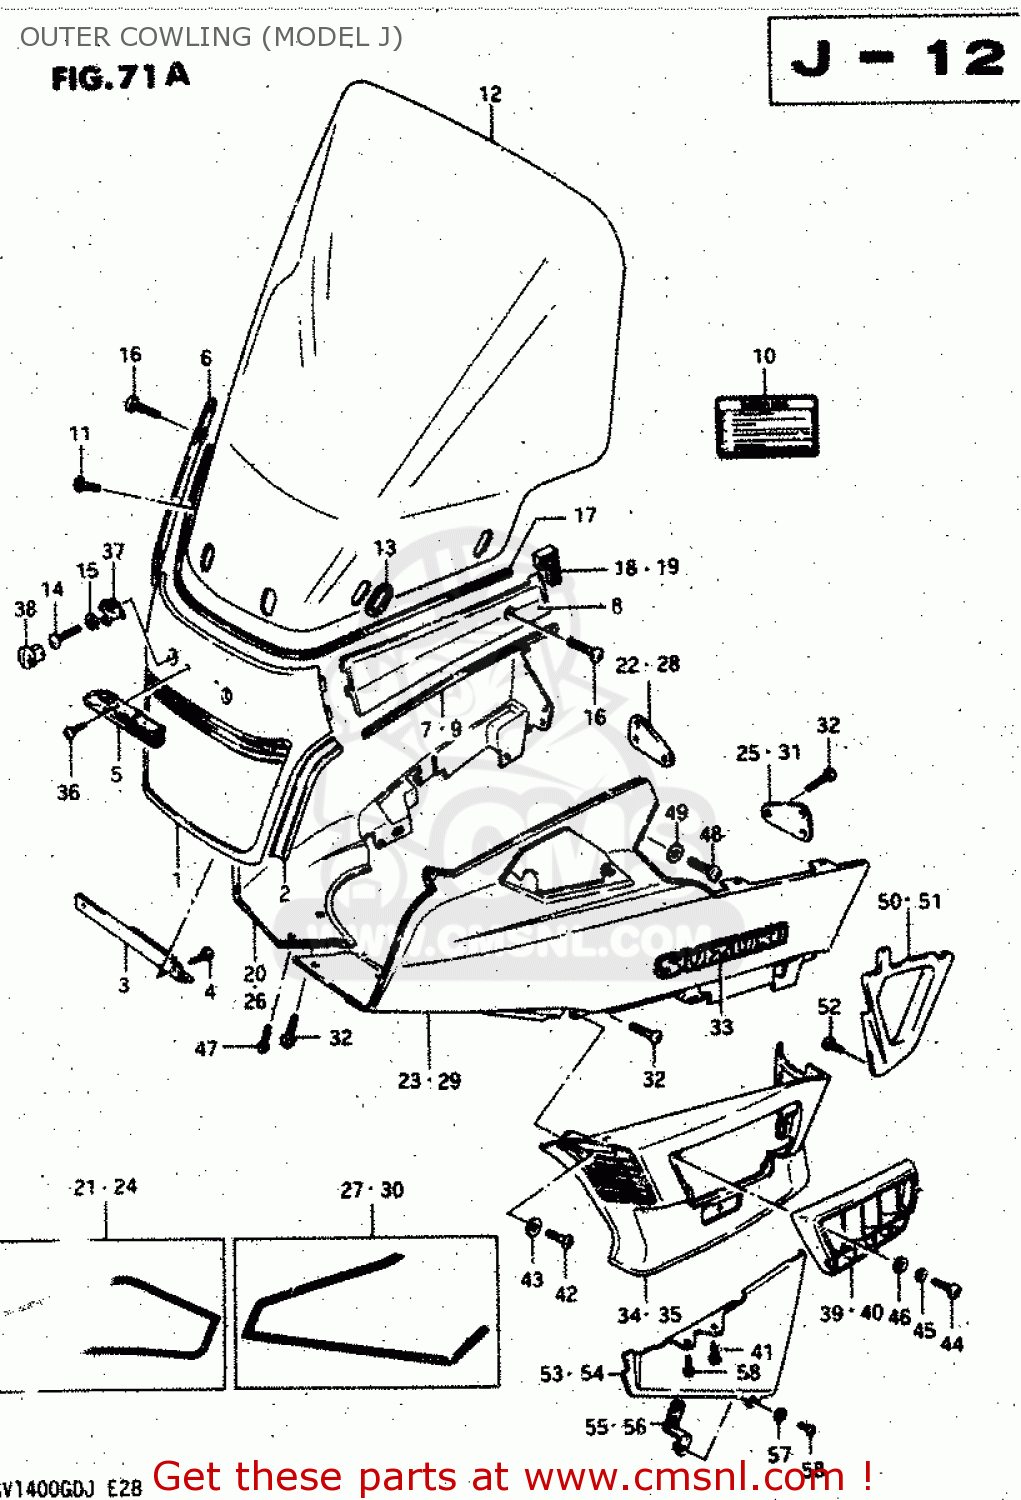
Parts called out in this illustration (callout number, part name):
1	COVER,COWLING,FRONT,CENTER
2	MOLDING,FRONT COVER,LOWER
3	BRACKET,FRONT,CENTER,UNDER
4	SCREW
5	EMBLEM,COWLING,FRONT
6	COVER,COWLING,FRONT,RIGHT
7	MOLDING,FRONT COVER SIDE
8	COVER, COWL FRONT LH
9	MOLDING,FRONT COVER SIDE
10	LABEL (WARNING SCREEN)
11	SCREW
12	SCREEN ASSY,COWLING
13	WASHER,SCREEN
14	SCREW
15	WASHER
16	SCREW
17	SEAL,FRONT COVER,CENTER
18	CAP,COWLING FRONT COVER END
19	CAP,COWL FR COVER END,L
20	BODY COMP,COWLING,RIGHT
21	TAPE SET,COWLING
22	BRACKET,COWLING BODY,RIGHT
23	BODY,COWLING,LEFT
24	TAPE SET,COWLING
25	BRACKET,COWLING BODY,RIGHT
26	BODY,COWLING,RIGHT
27	TAPE SET,COWLING
28	BRACKET,COWLING BODY,RIGHT
29	BODY,COWLING,LEFT
30	TAPE SET,COWLING
31	BRACKET,COWLING BODY,RIGHT
32	SCREW
33	EMBLEM,COWLING SIDE,LEFT
34	COVER ASSEMBLY,COWLING
35	COVER ASSEMBLY,COWLING SIDE,LEFT
36	SCREW
37	PLATE,FRONT COVER LOCK
38	CAP,FR COVER
39	LOUVER,SIDE COVER,RIGHT
40	LOUVER,SIDE COVER,LEFT
41	SCREW (M6X1X16)
42	SCREW
43	WASHER (4.3X13X0.80)
44	SCREW
45	LOCK WASHER
46	WASHER
47	SCREW
48	SCREW
49	WASHER
50	UNDER COVER, FRAME
51	COVER,COVER FRAME,UPPER
52	SCREW
53	COVER,COWLING SIDE,LOWER
54	COVER,COWLING SIDE,LOWER
55	BRACKET,COWLING SIDE,LOWER
56	BRACKET,COWLING SIDE,LOWER
57	WASHER
58	SCREW
